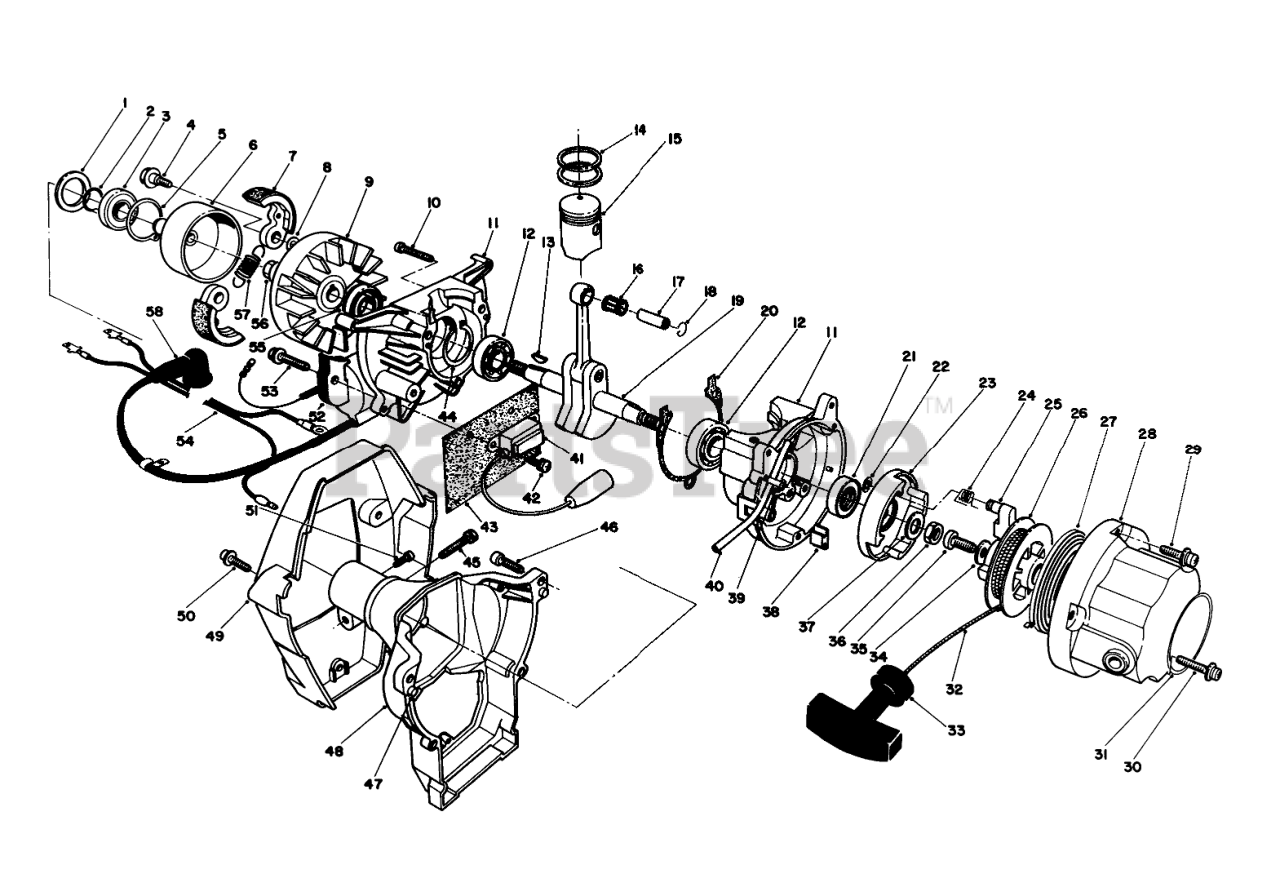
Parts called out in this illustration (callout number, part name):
1	Washer
2	SNAPRING
3	BEARING
4	CLUTCH BOLT
5	SNAPRING
6	Drum-Clutch
7	Shoe-Clutch
8	Washer
9	Flywheel
10	Screw
11	Crankcase Assembly (Incl. Ref. #10)
12	BEARING
14	PISTON RING
15	PISTON
16	NEEDLE BEARING
17	Pin-Piston
19	Crankshaft
20	Gasket-Crankcase
21	OIL SEAL
22	E-Ring
23	STARTER PULLEY
24	RETURN SPRING
25	RATCHET
27	SPRING
28	Case-Starter
29	SCREW W/WASHER
30	SCREW W/ WASHER
31	Decal
32	Rope-Starter
33	Knob-Starter
34	Washer
35	Screw
37	Washer
39	Clamp
40	Tube-Fuel
41	TRANSISTOR UNIT
42	SCREW W/ WASHER
43	Plate
44	Snap Ring
46	Screw
47	Knock Pin
48	Case-Clutch
49	Cover-Fan
50	Screw
51	Screw
53	BOLT AND WASHER
54	LEAD WIRE
55	Oil Seal
57	Spring
58	CAP-PLUG
